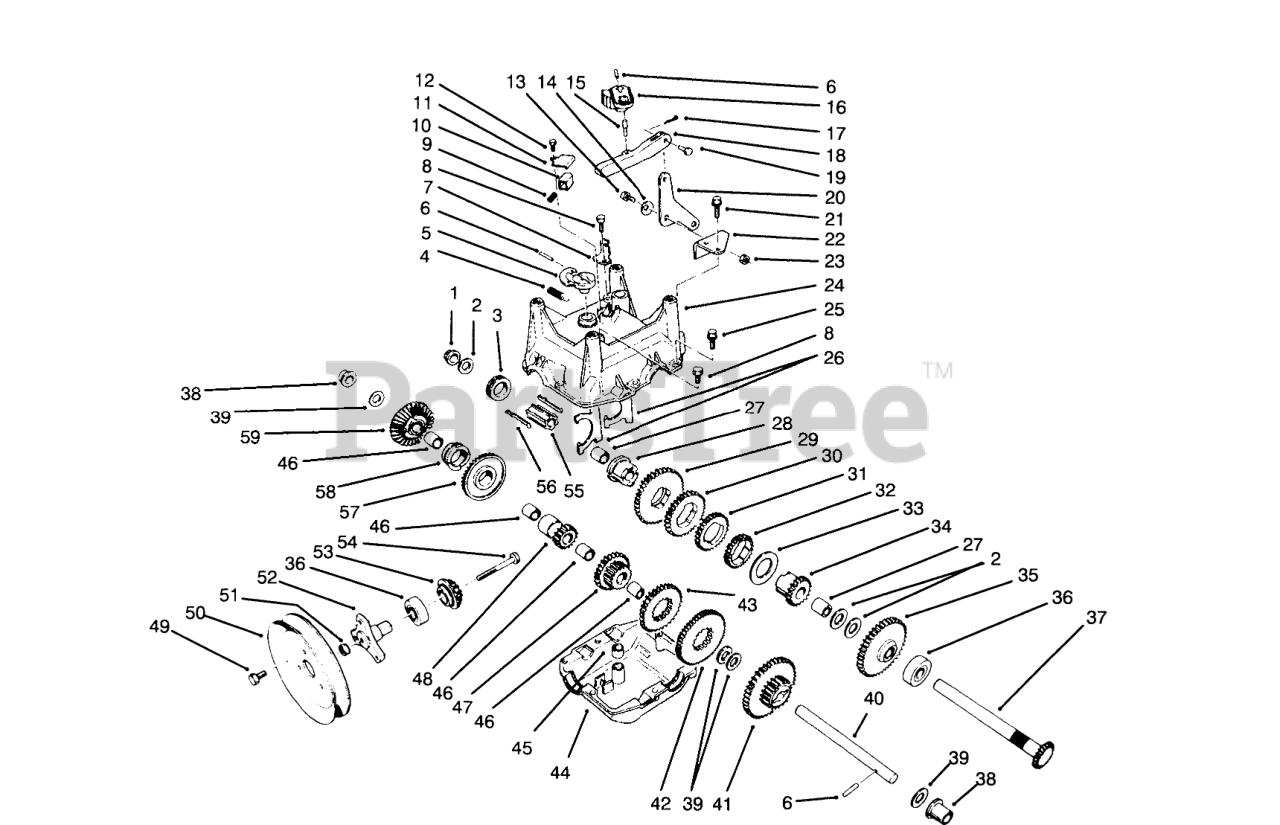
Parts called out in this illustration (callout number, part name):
1	BUSHING-FLANGE, OUTPUT
2	BEARING-THRUST
3	COLLAR-SHIFT
4	SPRING-EXTENSION
5	LEVER
6	PIN-SPRING
7	BRACKET-CABLE
8	SCREW-HWH
9	SPRING-DETENT
10	BUTTON-DETENT
11	COVER-DETENT
12	SCREW-HWH
13	SCREW-SHOULDER
14	WASHER-CURVED
15	PIN-LINK, GEAR SHIFT
16	LEVER-SHIFT, GEAR
17	PIN-COTTER
18	LINK-SHIFT, GEAR
19	PIN-CLEVIS
20	BELLCRANK
21	SCREW-HWH
22	BRACKET-BELLCRANK
23	NUT-LOCK, NI
24	GEARCASE-UPPER, CASING
25	SCREW-HWHTF
26	YOKE-SHIFT
27	BUSHING-OUTPUT
28	SLEEVE-GEAR
29	GEAR-45 T
30	GEAR-34 T
31	GEAR-27 T
32	GEAR-29 T
33	WASHER-THRUST
34	GEAR-SLEEVE, 19 T
35	GEAR-41 T
36	BEARING-BALL
37	SHAFT-OUTPUT
38	BUSHING-INTERMEDIATE
39	WASHER-THRUST
40	SHAFT-INTERMEDIATE
41	GEAR-19/41 T
42	GEAR-51 T
43	GEAR-33 T
44	GEARCASE-LOWER, CASING
45	BUSHING-YOKE
46	Bushing-Output
47	GEAR-26 T
48	GEAR-BEVEL, 15 T
49	SCREW
50	TRACTION-SHEAVE, HALF
51	NUT-HHF
52	HUB-PULLEY
53	PINION-BEVEL
54	SCREW-HH
55	SLEEVE-SHIFT
56	KEY-SHIFT
57	GEAR-BEVEL, 36 T
58	COLLAR-SHIFT
59	Gear-Bevel Reverse 36T (Incl. Ref. #46)
